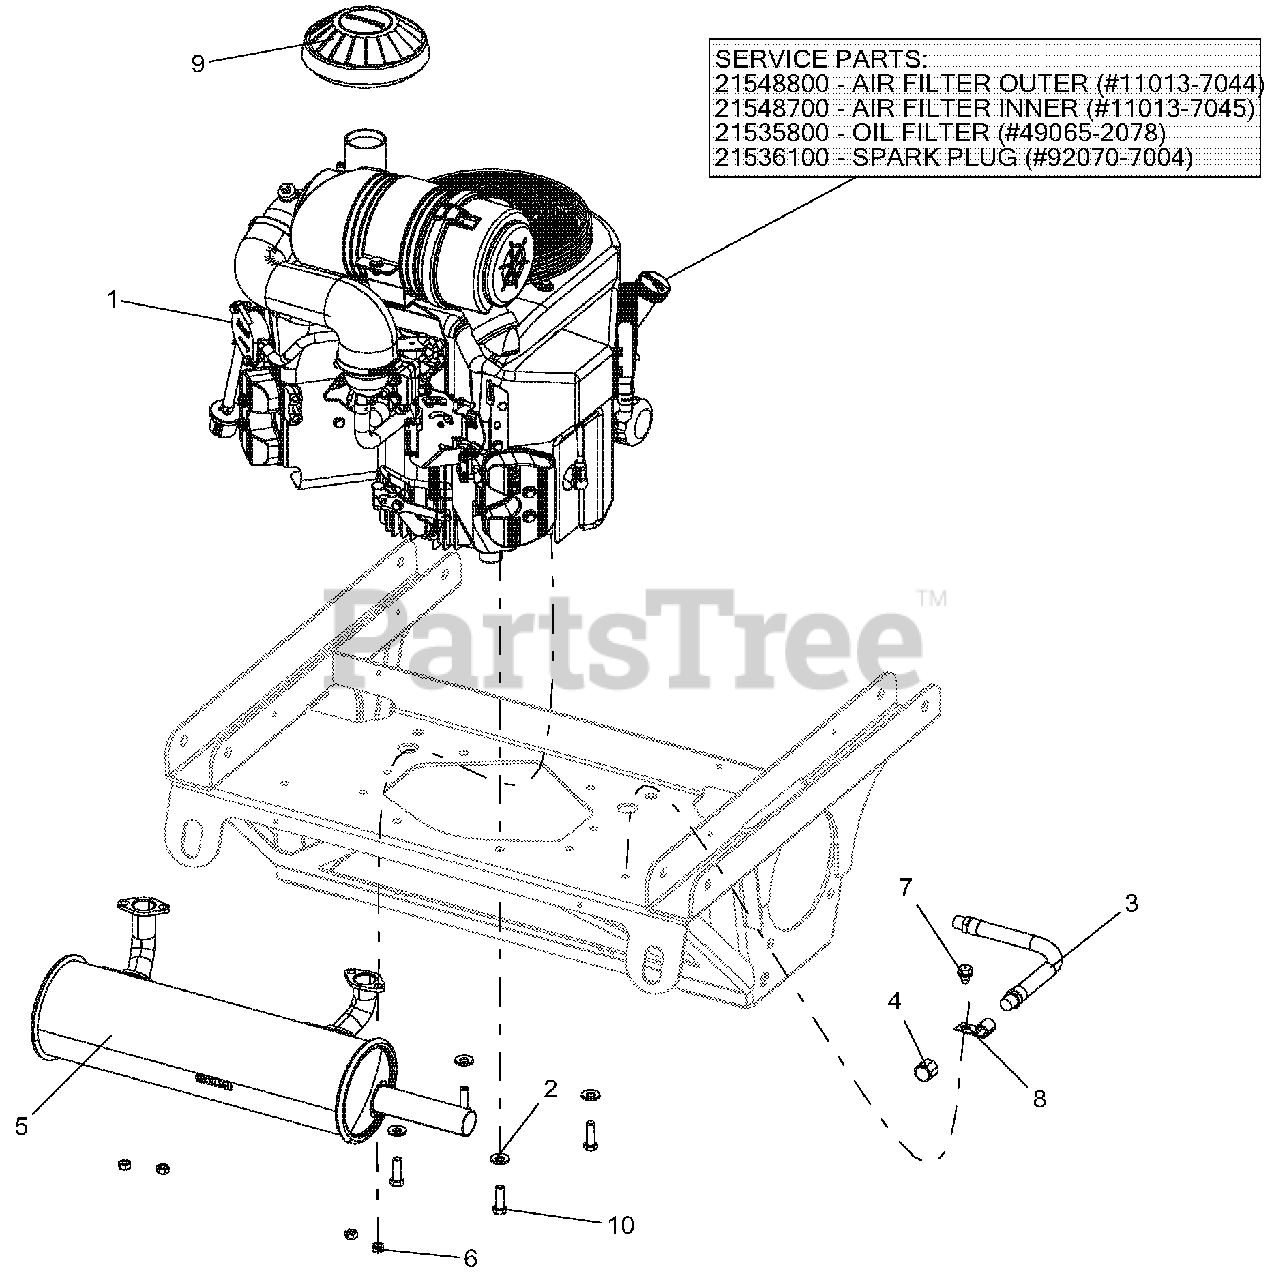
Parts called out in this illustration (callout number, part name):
1	ENGINE, ENVIROGUARD LP CONVERSION
1	AIR FILTER OUTER (#11013-7044)
1	AIR FILTER INNER (#11013-7045)
1	OIL FILTER (#49065-2078)
1	SPARK PLUG (#92070-7004)
2	WSHR, 3/8" SPRING DISC
3	HOSE, HYD .38-11-0K M6N0-M6NO
4	PIPE, CAP 3/8 NPT FEMALE
5	MUFFLER, 27-31 FX KAW
6	NUT-LK-TOP M8-1.25 YWZC
7	SCR-TAP .38-16X.50 HWH TR YWZ
9	CAP, AIR CLEANER INTAKE (2")
10	BLT-HEX .38-16X1.25 GR5 YWZC NYTORQ
